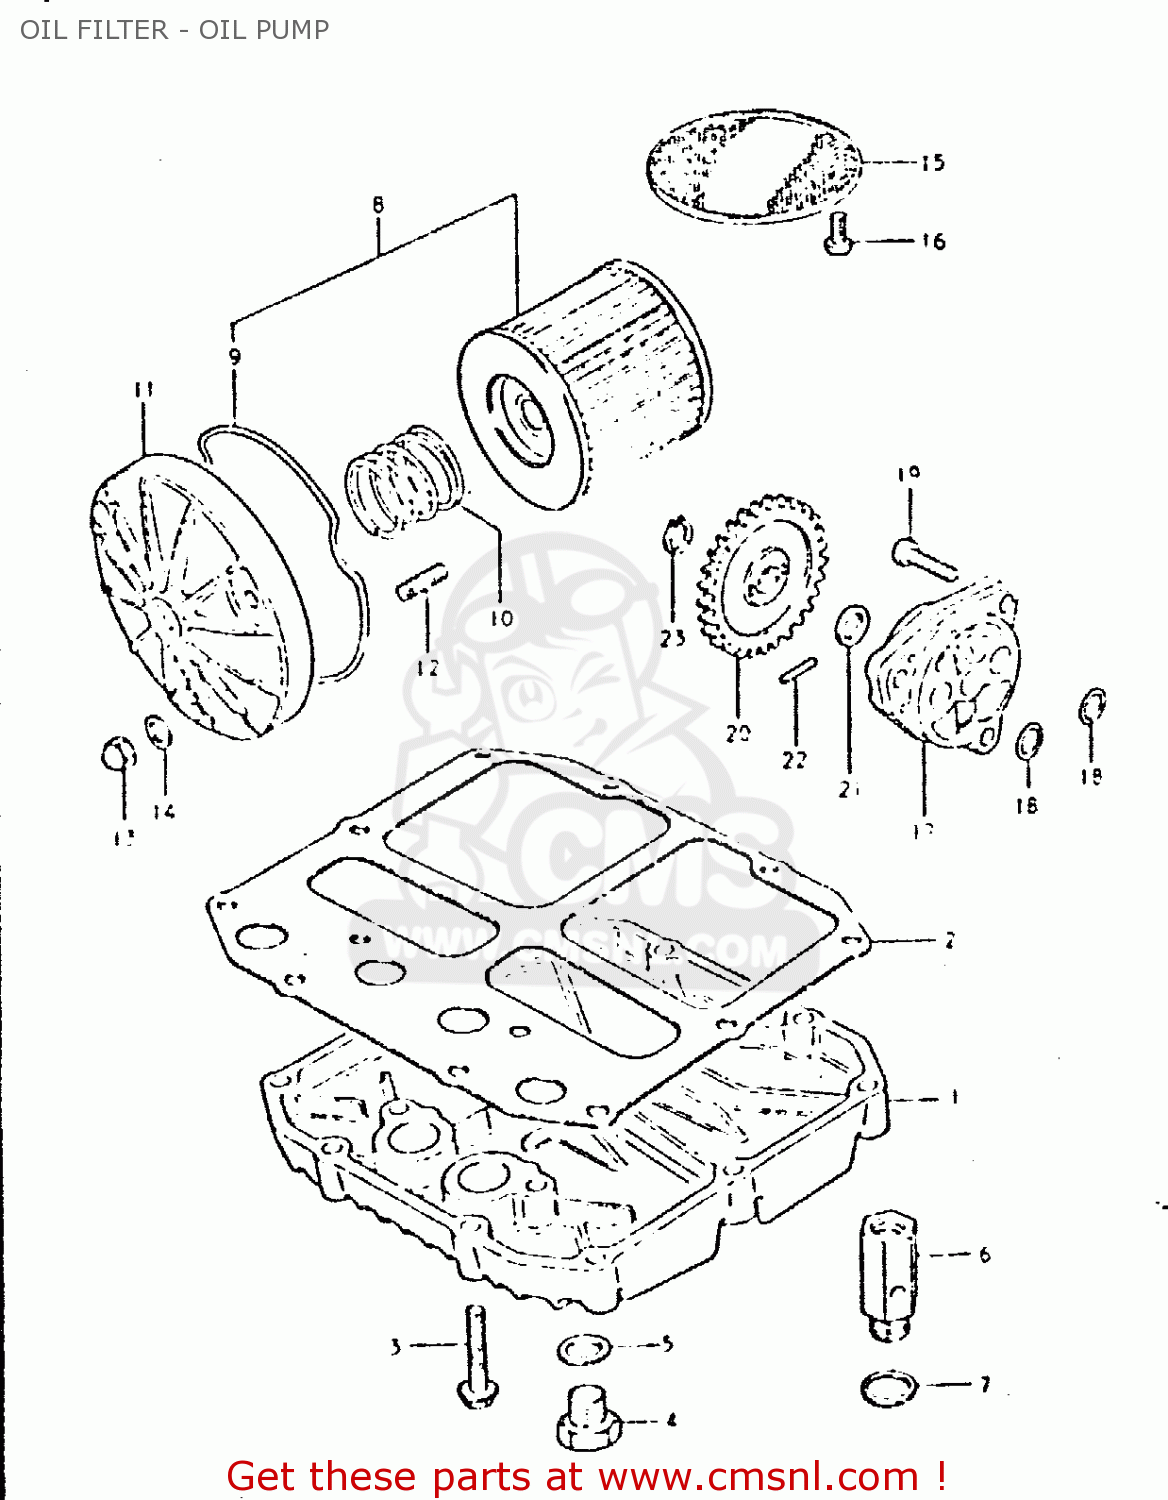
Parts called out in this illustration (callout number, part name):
1	PAN,OIL
2	GASKET,OIL PAN (MCA)
3	BOLT
4	PLUG
5	GASKET(14X19.2X2) (NAS)
6	REGULATOR ASSEMBLY,ENGINE
7	WASHER
8	ENGINE OIL FILTER SET
9	O RING,OIL FILTER CHAMBER CAP
10	SPRING
11	CAP,OIL FILTER
12	STUD 6X20
13	NUT
14	WASHER
15	STRAINER,ENGINE OIL
16	SCREW 6X12
17	PUMP ASSY,ENGINE OIL
18	O RING(D:1.9,ID:13)
19	SCREW
20	GEAR,OIL PUMP DRIVEN
21	SHIM
22	PIN(4X15.8)
23	CIRCLIP
